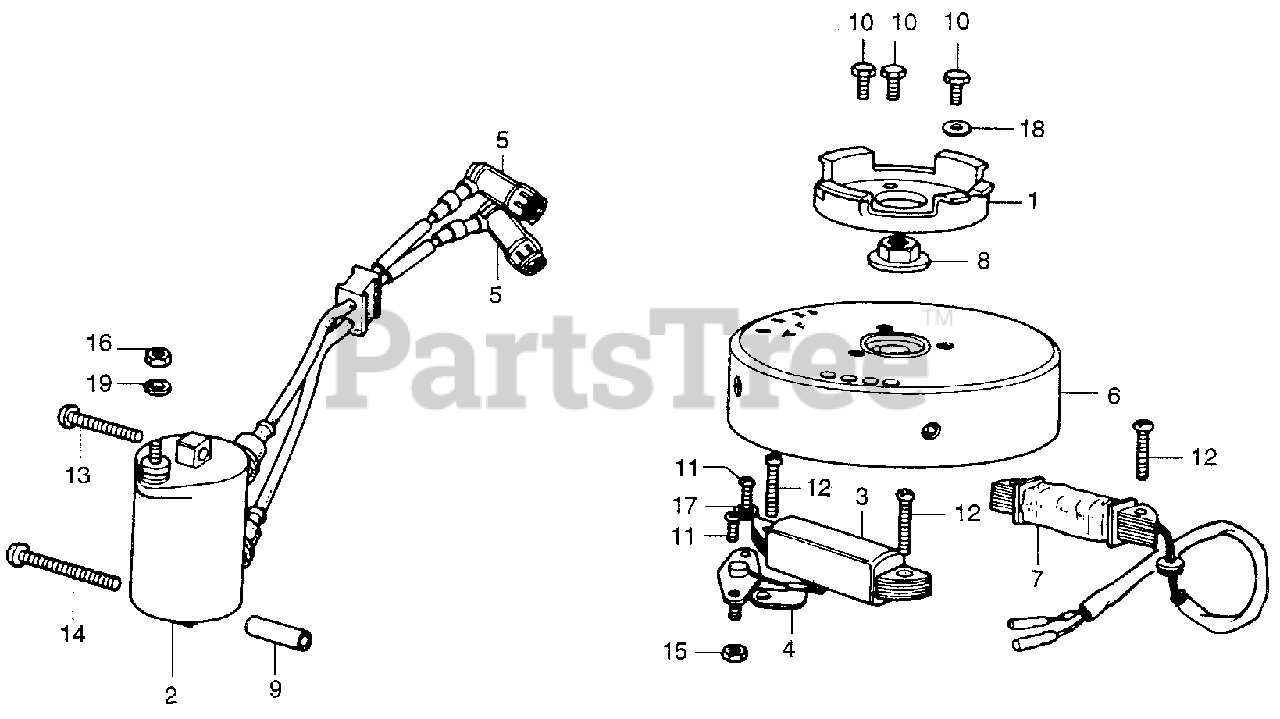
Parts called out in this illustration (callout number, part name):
1	PULLEY, STARTER RATCHET *R8* (BRIGHT RED) (NOT AVAILABLE)
2	COIL ASSY., A.C. IGNITION (NOT AVAILABLE)
3	COIL ASSY., PRIMARY
5	CAP ASSY., NOISE SUPPRESSOR
5	CAP ASSY., PLUG
6	FLYWHEEL
8	NUT, SPECIAL (12MM) (NOT AVAILABLE)
9	COLLAR, DISTANCE (6.5MM)
10	BOLT, HEX. (6X10) (NOT AVAILABLE)
11	SCREW, PAN (5X12)
12	SCREW, PAN (5X25)
13	SCREW, PAN (6X20)
14	SCREW, PAN (4X45)
15	NUT, HEX. (5MM)
16	NUT, HEX. (5MM)
17	WASHER, PLAIN (5MM)
19	WASHER, SPRING (5MM)
